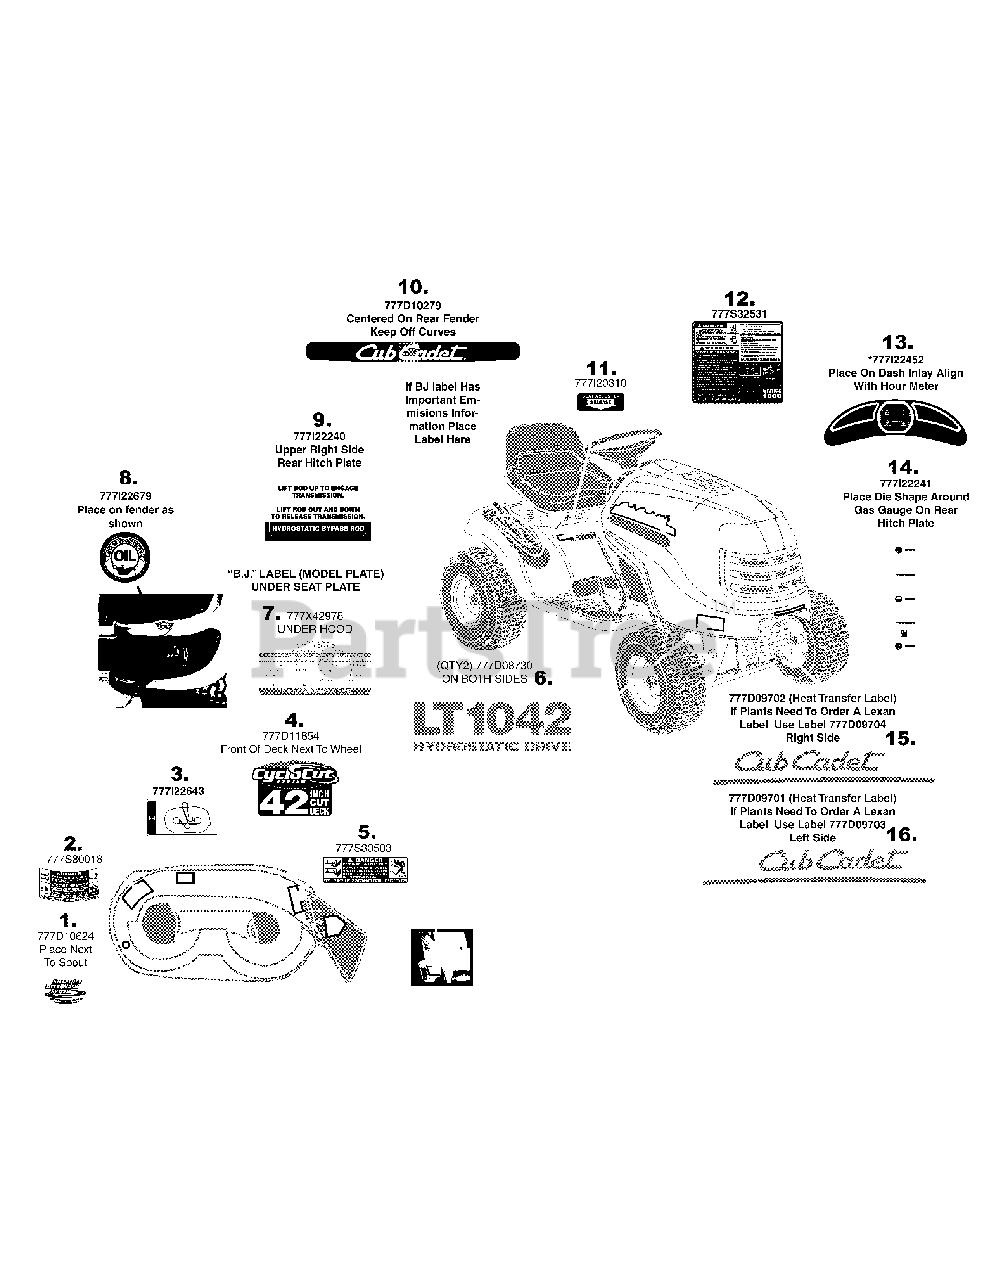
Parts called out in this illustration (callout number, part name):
1	LABEL-RIDER:DECK WASH CUB
2	LABEL-DECK SAFETY
3	LABEL-DECK BELT ROUTE 42"
4	LABEL-RIDER DECK 42" CUB BLUE
5	LABEL-DANGER CHUTE
6	LABEL-MODEL LT1042
7	LABEL-PARTS LIST LT1042
8	LABEL-CHECK ENG OIL
9	LABEL-HYDRO ENGAGE
10	LABEL-REAR FENDER
11	LABEL-SEAT ADJUSTE
12	LABEL-FRAME COVER
13	LABEL-DASH PANEL
14	LABEL-FUEL LEVEL
15	LABEL-RGT SIDE HOOD
16	LABEL-LFT SIDE HOOD
